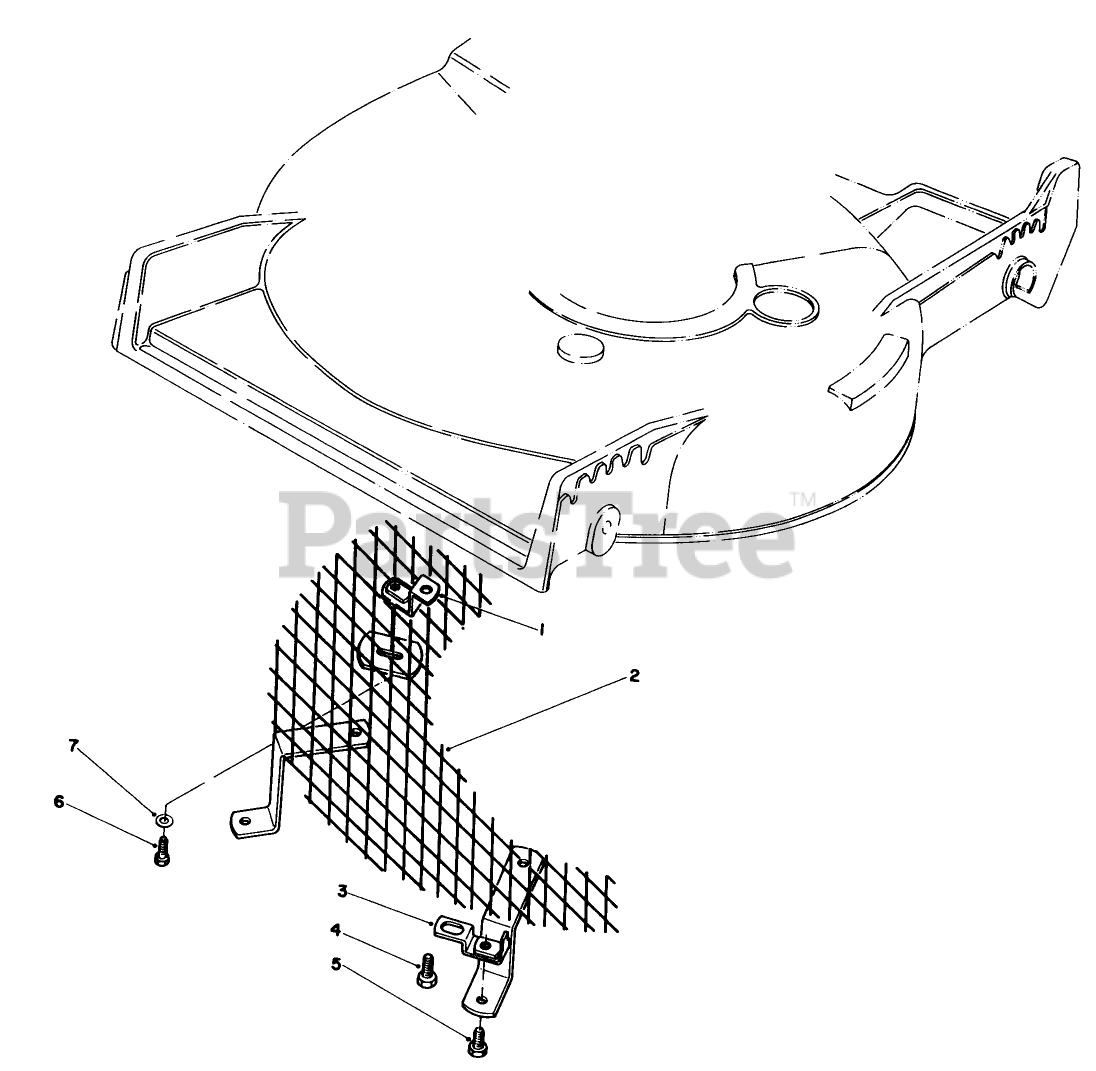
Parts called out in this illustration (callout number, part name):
1	BRACKET WA
2	Screen
3	MTG. BRACKET W.A.
4	SCREW-THD ROLL, HWH
5	SCREW-HH
6	SCREW-HH
7	WASHER-FLAT
